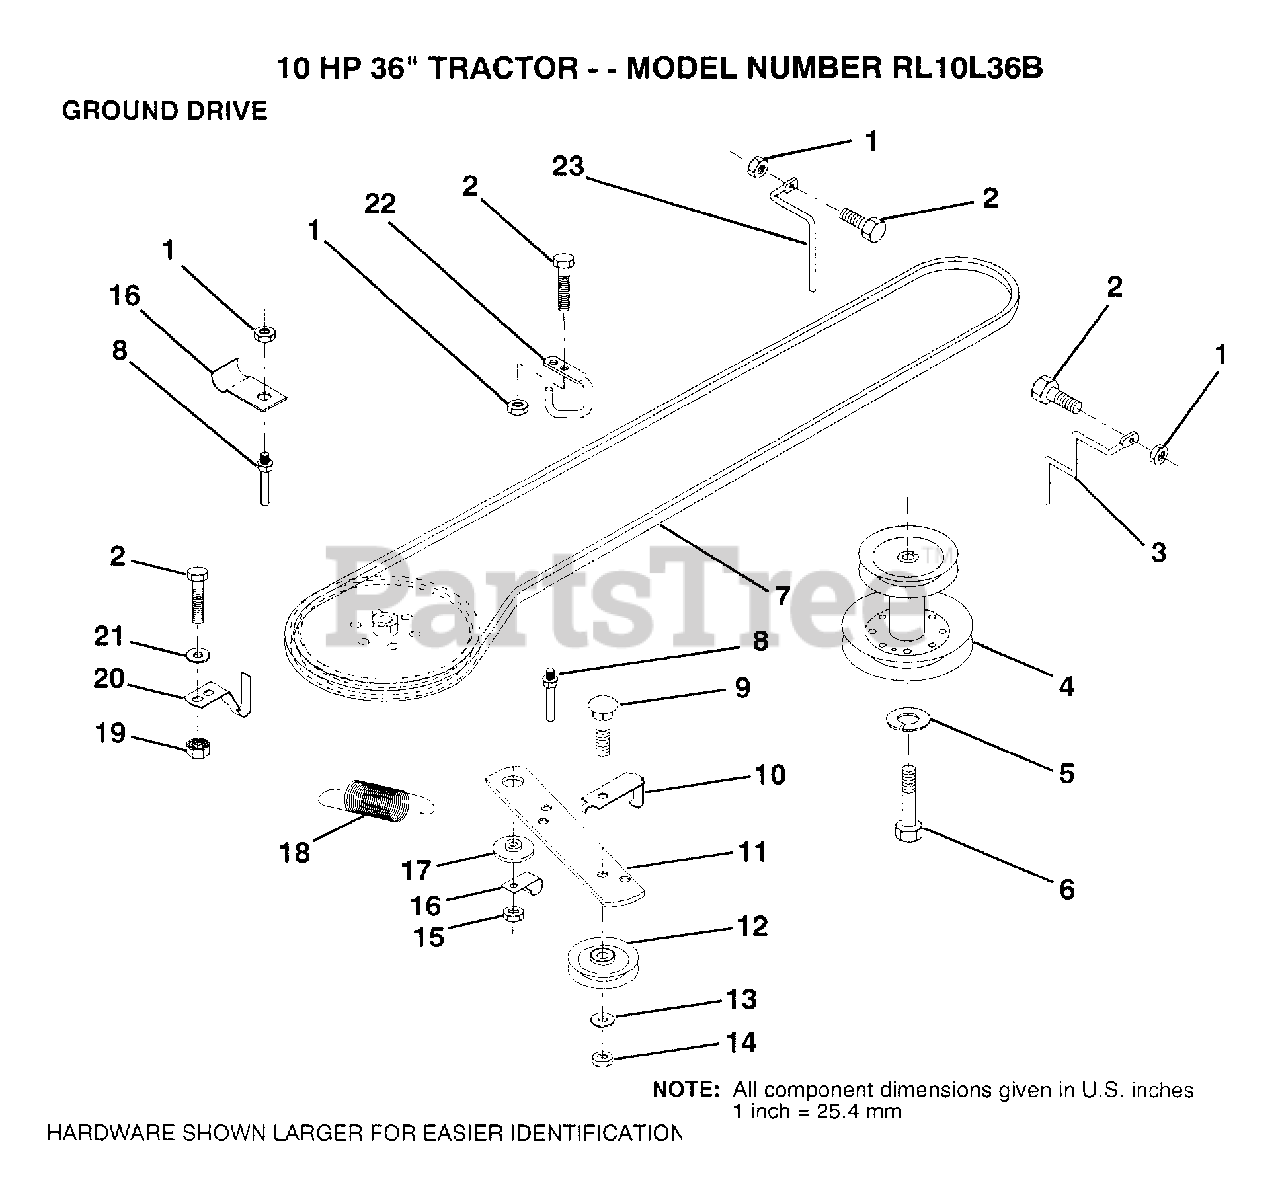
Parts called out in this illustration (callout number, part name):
2	BOLT
5	LOCKWASHER
6	HEX BOLT
7	BELT
8	"KEEPER,DRIVE BELT"
9	BOLT
10	"KEEP,IDLER DR BEL"
12	PULLEY.IDLER.FLAT
13	WASHER
14	LOCKNUT
16	"CLIP,INSULATOR"
17	SPACER RETAINER
20	"KEEPER,DR BELT "
21	WASHER
22	"KEEPER,FRA DR BEL"
